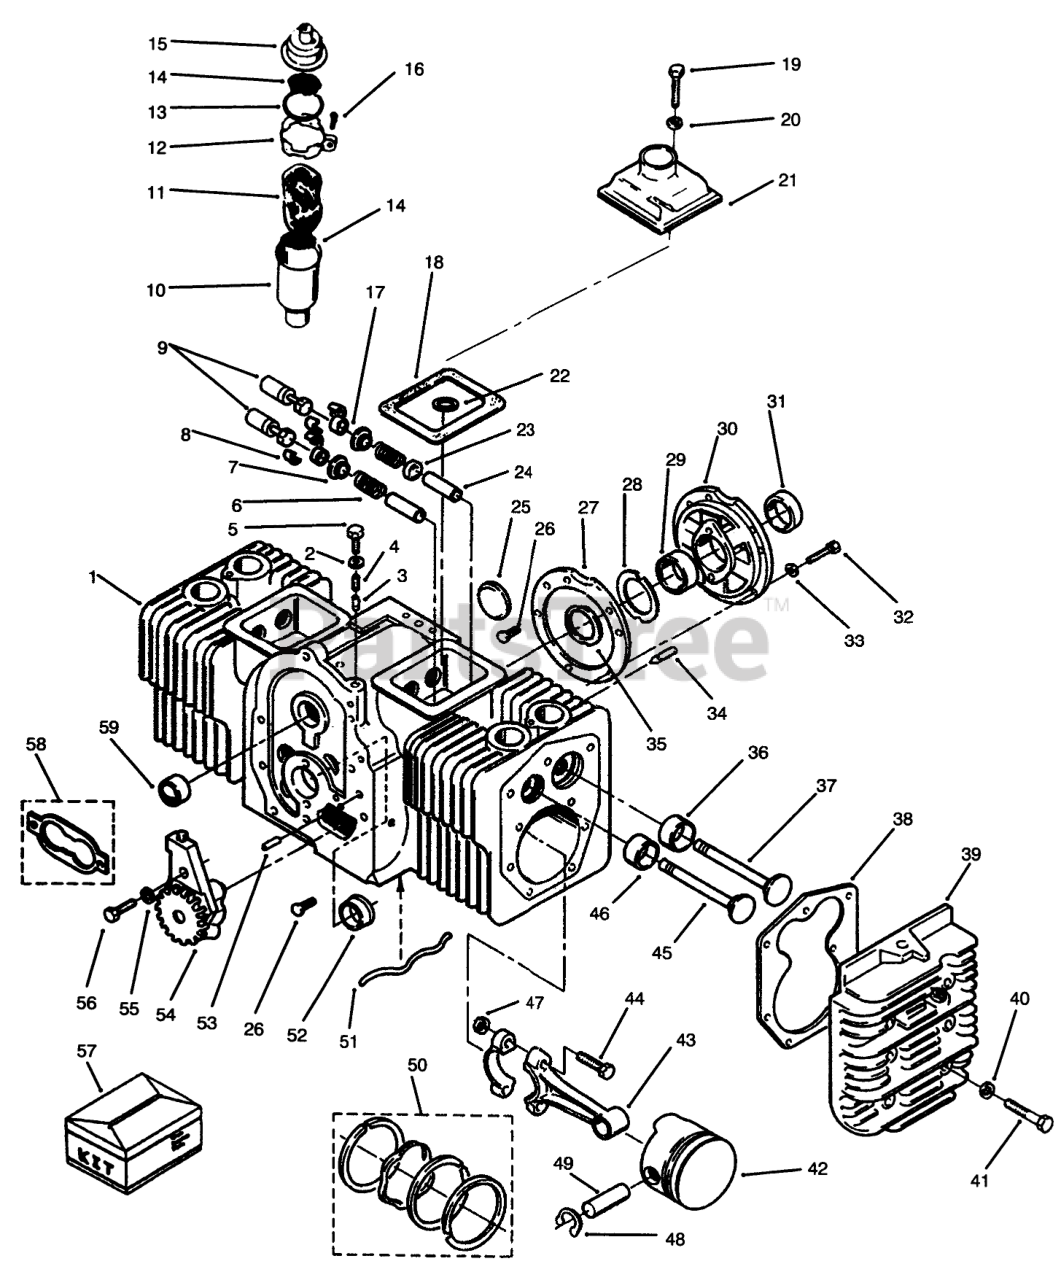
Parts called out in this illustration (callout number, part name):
1	CYLINDER BLOCK
2	WASHER
3	PLUNGER
4	SPRING
5	SCREW-HH
6	VALVE SPRING
7	VALVE SPRING RETAINER
8	VALVE SPRING LOCK
9	Tappet-Valve
9	TAPPET
9	TAPPET .002 OS
10	TUBE-BREATHER
11	FILTER
12	Clamp
13	SEAL - O-RING
14	SCREEN-BREATHER TUBE
15	BREATHER-CAP AND VALVE
16	SCREW-TAPPING, ROUND HEAD
17	VALVE CAP
18	GASKET
19	HHCS 1/4-20 X 1 3/4
20	WASHER
21	VALVE-COVER L.H.
22	WASHER-FLAT
23	VALVE STEM SEAL
24	EXHAUST VALVE GUIDE
24	INTAKE VALVE GUIDE
26	PIN-DRIVE
27	GASKET
29	BEARING KIT (STANDARD SLEEVE)
29	BEARING-CRANKSHAFT (.002)
29	BEARING KIT (.010)
29	BEARING-CRANKSHAFT (.020)
29	BEARING-CRANKSHAFT (.030)
30	PLATE-BEARING, REAR
32	HEX HD CAPSCREW
33	WASHER-LOCK
33	WASHER-FLAT
34	SCREW-SET
35	WASHER
36	Insert-Valve Seat, Intake
36	STD INSERT
36	INSERT .010
37	INTAKE VALVE
38	GASKET
39	HOUSING CYL RH
39	CYL RS HEAD
39	LH CYLINDER HEAD
40	WASHER
41	Screw-HH
42	STD PISTON KIT
42	PISTON .010
42	PISTON .020
42	PISTON .030
43	CONN ROD ASM
43	ROD .03 US
45	EXHAUST VALVE
46	Insert-Valve Seat, Exhaust
46	STD INSERT
46	INSERT .002
46	INSERT .005
46	INSERT .010
46	.025" Oversize
48	Piston Pin
49	PISTON PIN
50	Kit-Ring, Piston
50	RING/PISTON KIT
50	RING/PISTON KIT .050
50	RING/PISTON KIT .010
50	RING/PISTON KIT .020
50	RING/PISTON KIT .030
51	OIL TUBE
52	Bearing-Crankshaft, Front, Flanged
52	KIT-BEARING, SLEEVE
52	BEARING-CRANKSHAFT
52	BEARING KIT (.010)
53	PIN-GEAR COVER
55	WASHER-FLAT
56	SCREW - CAP HEX HEAD
57	ENGINE GASKET KIT
58	GASKET KIT
59	SLEEVE-BEARING
